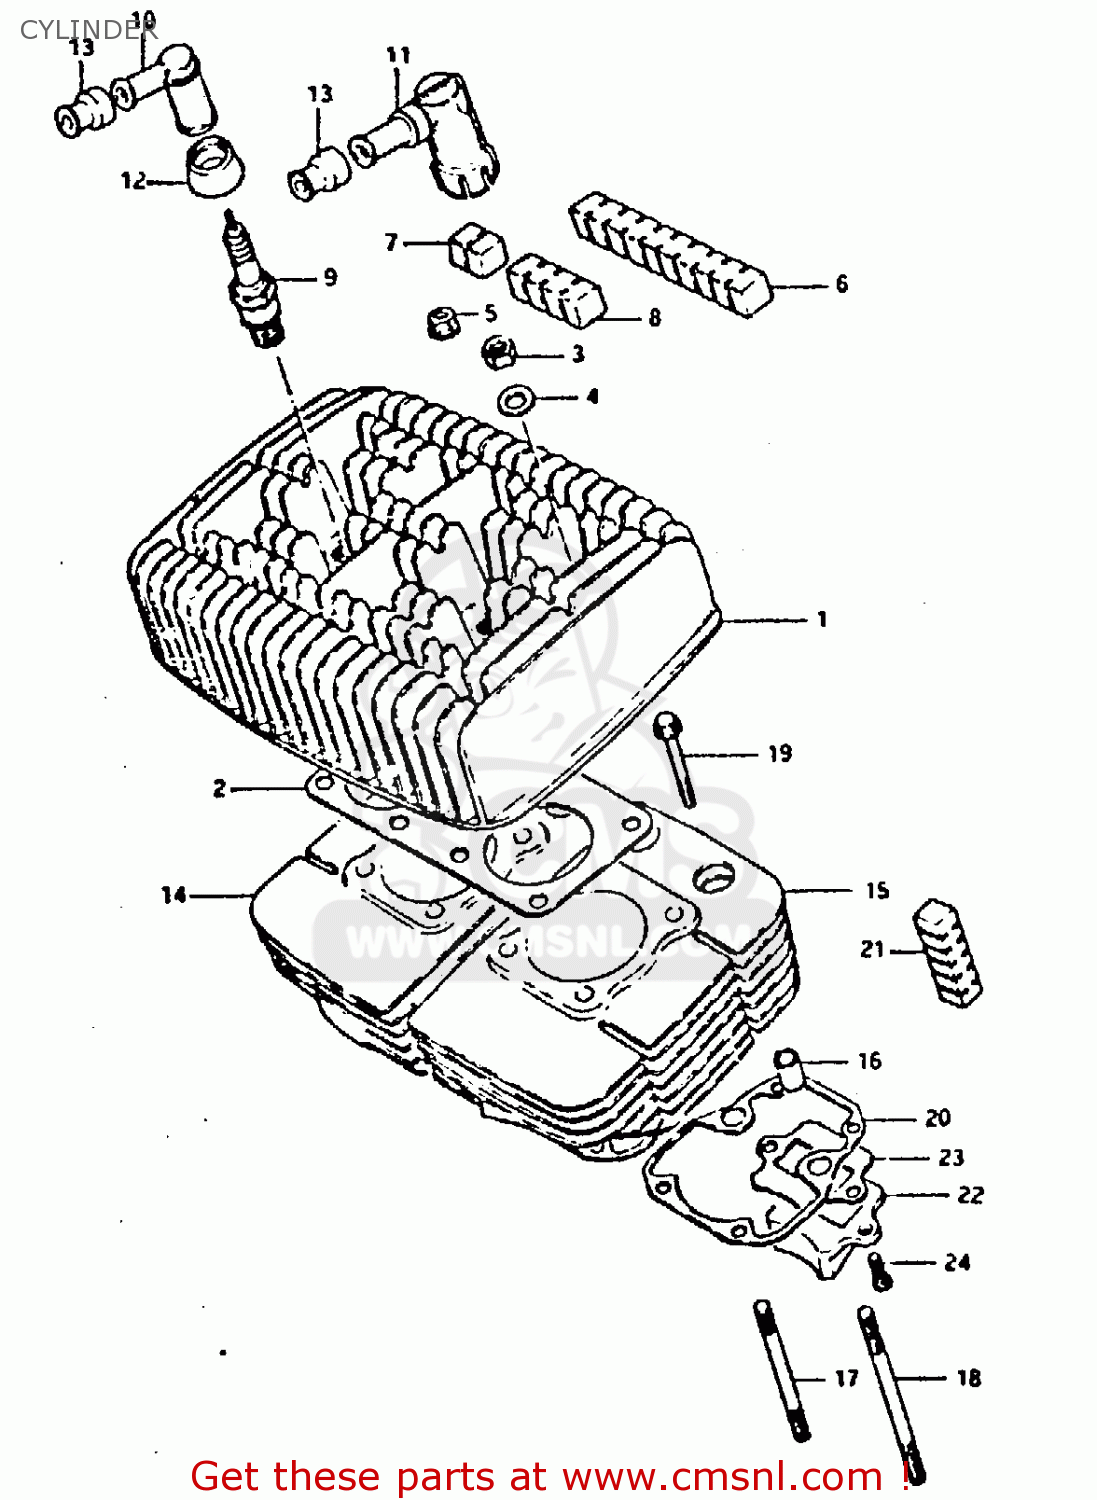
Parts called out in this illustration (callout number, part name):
1	CYLINDER HEAD
2	GASKET,CYLINDER HEAD (NAS)
3	NUT
4	WASHER
5	NUT
6	PAD,CYLINDER
7	PAD,CYLINDER
8	PAD,CYLINDER
9	SPARK PLUG
10	CAP ASSY,SPARK PLUG
12	SEAL,SPARK PLUG
13	SEAL,SPARK PLU
14	CYLINDER,RH
15	CYLINDER,LH
16	PIN
17	BOLT,STUD
18	BOLT,STUD
19	BOLT ,6X50
20	GASKET, CYLINDER (MCA)
21	RUBBER PAD, CYLINDER (1)
22	VALVE ASSY,REED
23	GASKET (MCA)
24	SCREW
